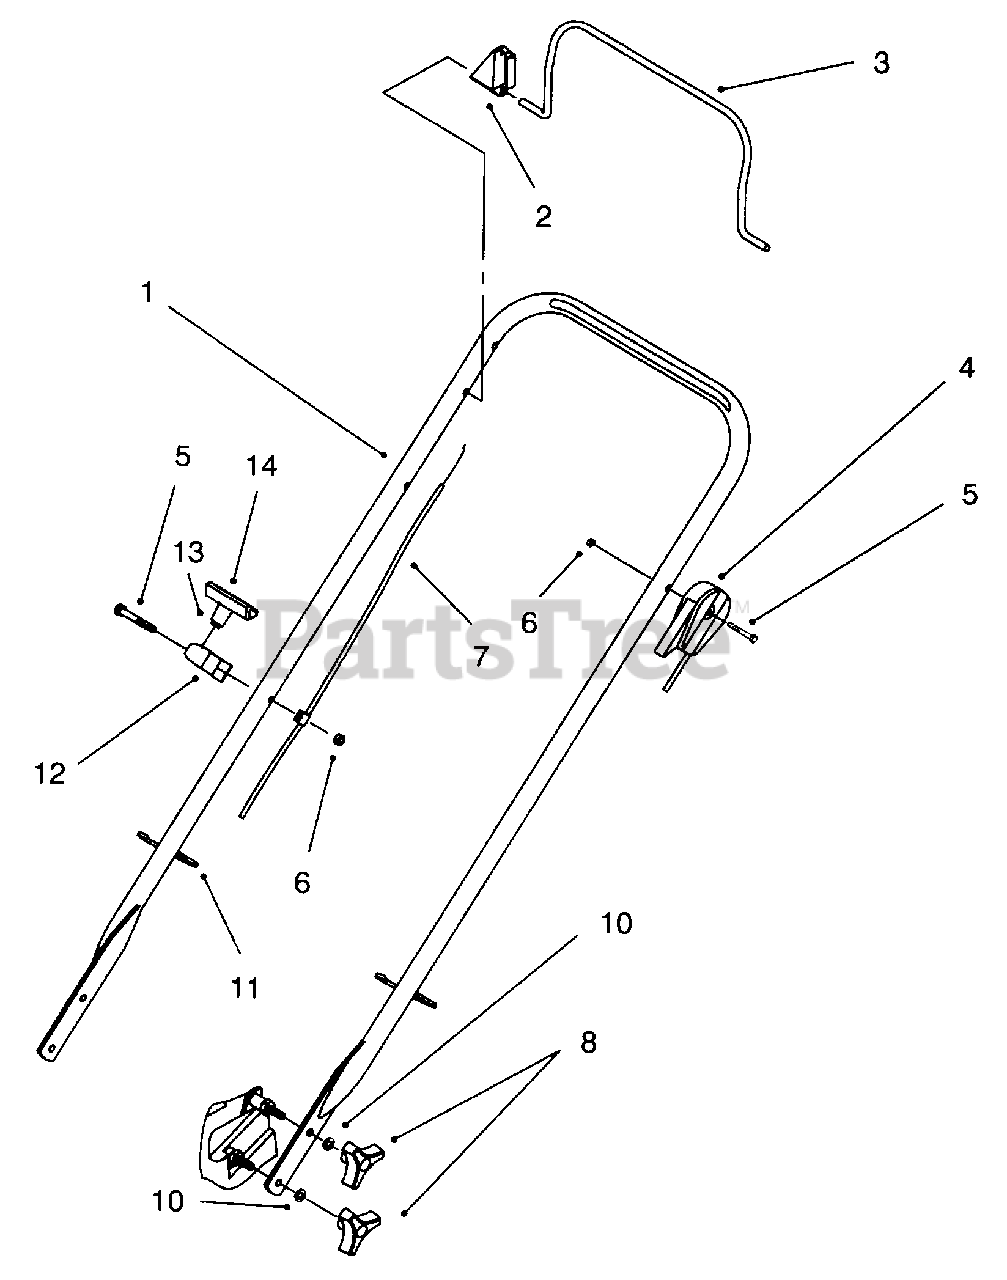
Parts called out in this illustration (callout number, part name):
2	Stop-Pivot
3	Bail-Flywheel Brake
4	Cable-Throttle
5	Screw-Hex Hd. Cap
6	Nut-Lock
7	Cable-Brake
8	Knob
10	Washer-Lock
11	Tie-Cable
12	Guide-Rope
13	Handle-Starter
14	Clip-Rope Insert
